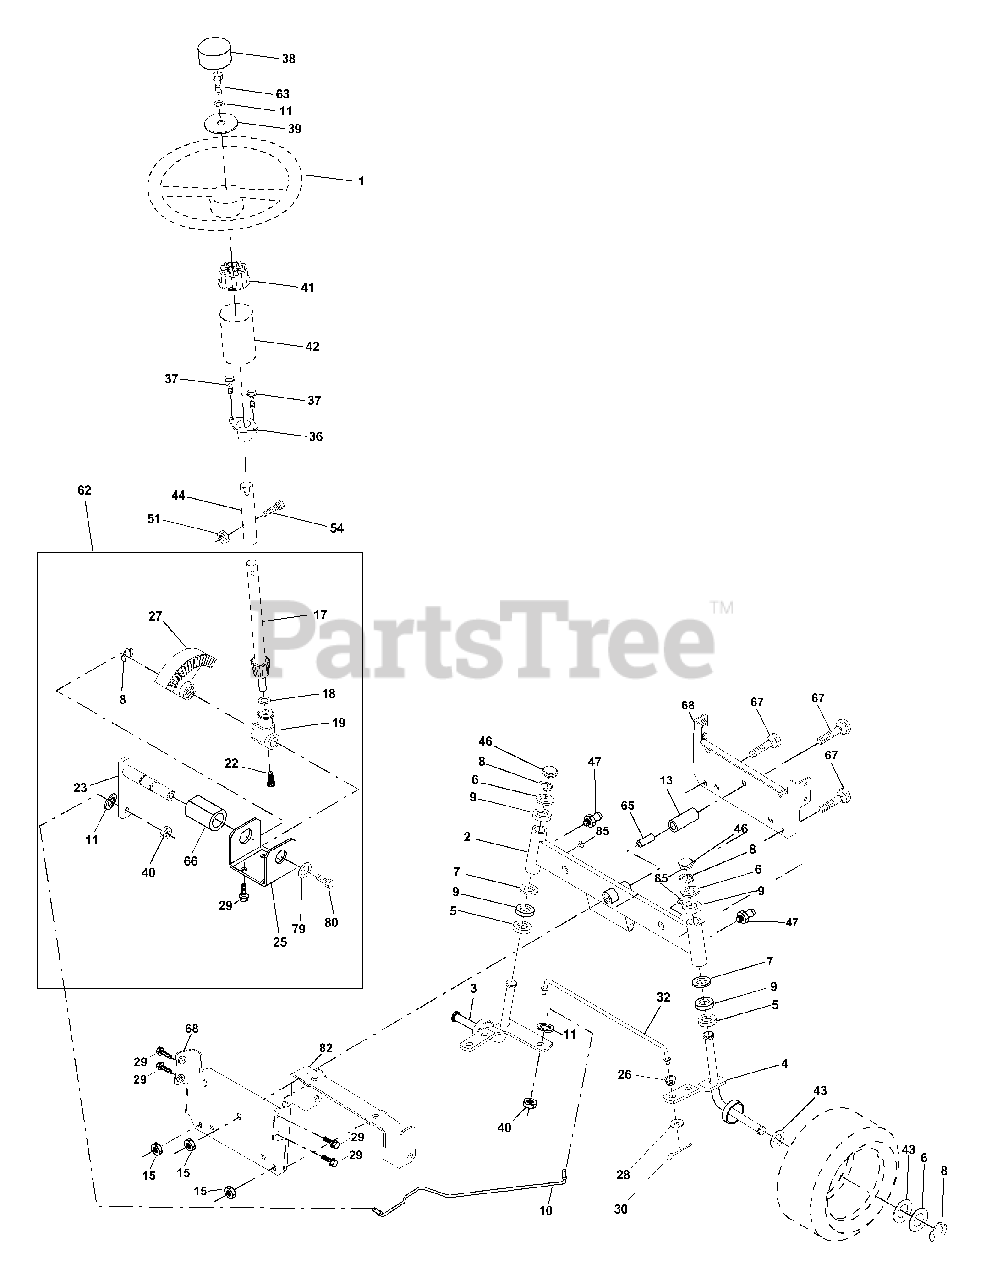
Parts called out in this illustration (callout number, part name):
1	Wheel Steering
2	Axle Asm STMP Dropped STL
3	Spindle Asm LH
4	Spindle Asm RH
5	Bearing Race Thrust Harden
6	Washer 25/32 X 1-5/8 X 16 Ga
7	Washer 27/32 X 1-1/4 X 16 Ga
8	Ring Klip #t5304-75
9	Bearing Col Strg Blk
11	Washer Lock Hvy Hlcl Spr 3/8
13	Spacer Brg Axle Front
15	Nut Hex Flange Lock
17	Shaft Asm Strg
18	Washer Thrust 515x 750x 033
19	Support Shaft
22	Screw Hex Wsh Hd Torx
23	Shaft Asm Pittman
25	Bracket Steering
26	Bushing Link Drag Blk LR
27	Gear Sector
28	Washer 13/32 X 7/8 X 16 Ga
29	Screw 3/8-16x3/4
30	Pin Cotter 1/8 X 3/4 Cad
32	Rod Tie Wire Form 19 75 Mech
36	Bushing Strg
38	Cap Wheel Steering
39	Washer 13/32 X 2-3/8 X 12 Ga
40	Lock nut
41	Adaptor Wheel Strg
42	Boot Steering Shaft
43	Washer 25/32 X 1 1/4 X 16 Ga
44	Extension Steering Shaft LR/LT
46	Cap Spindle Fr Top Blk
47	Fitting Grease
51	Nut Lock Hex w/Ins 5/16-18
54	Bolt Fin Hex 5/16-18 Unc x 1-1/4
62	Kit, Steering Assembly Svc
63	Bolt Fin Hex 3/8-16unc x 1 Gr. 5
65	Spacer Brace Axle
66	Bearing Arm Pittman
67	Bolt Rdhd Sq 3/8-16 x 2-1/4
68	Axle, Brace
79	Washer 13/32 x 1-1/4 x 12 Ga.
80	Bolt Hex Nylon 3/8-16 x 3/4
82	Bracket Susp Chassis Front
85	Fastner Christmas Tree
